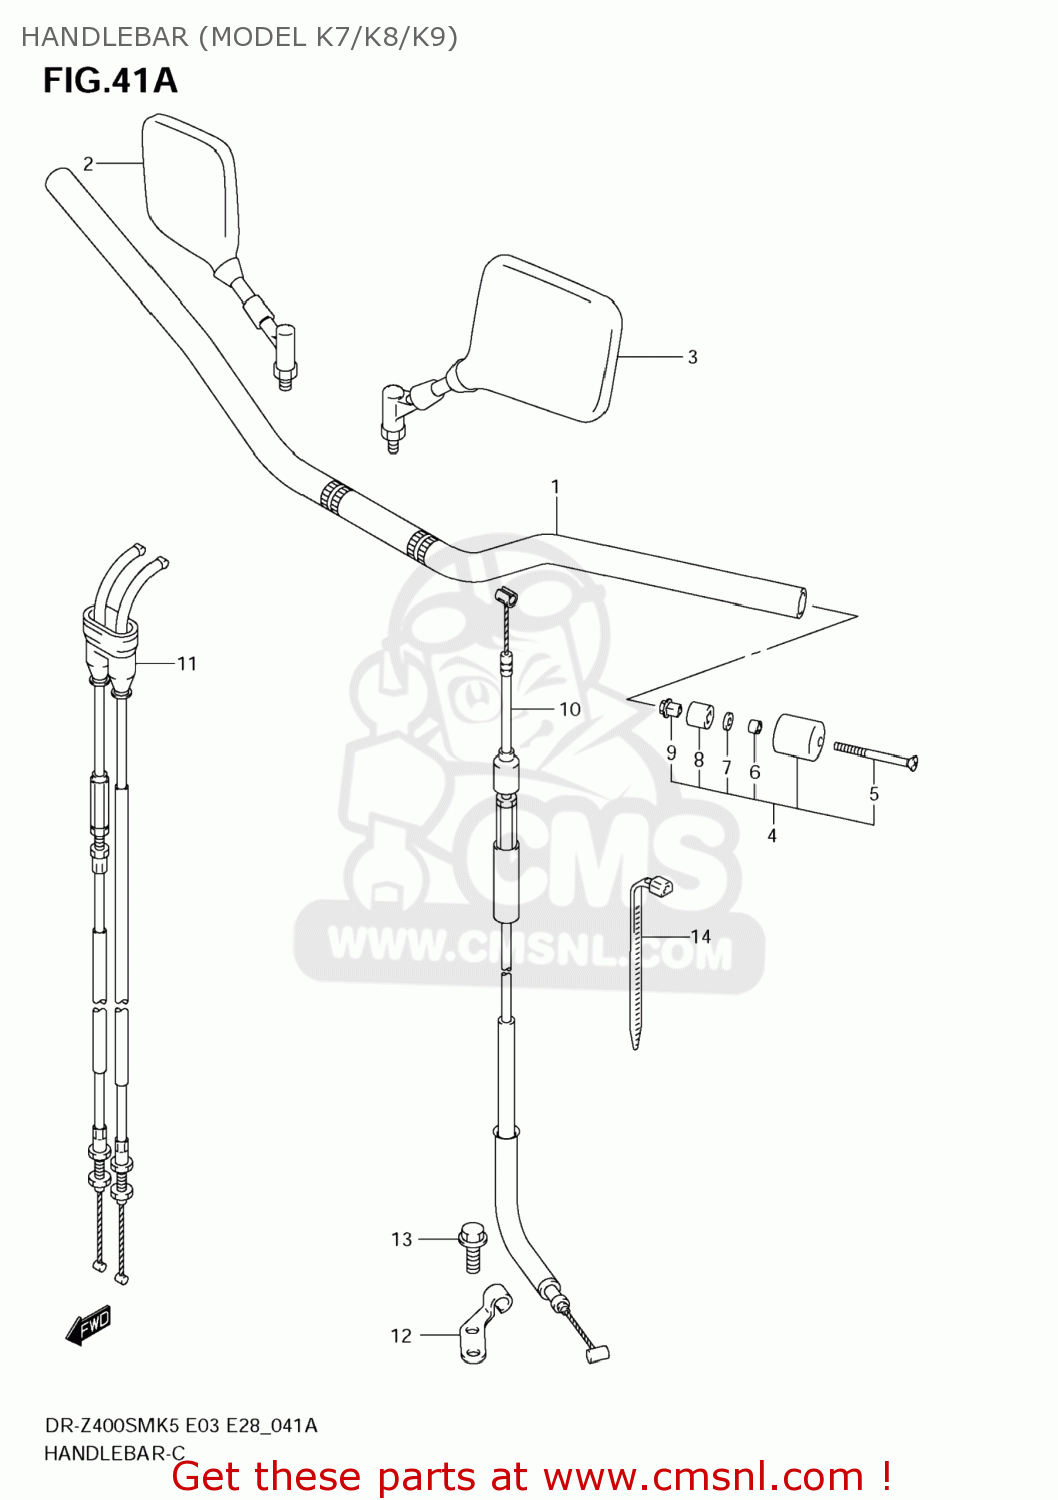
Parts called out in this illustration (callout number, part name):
1	HANDLEBAR
2	MIRROR ASSY,RR VIEW,R
3	MIRROR ASSY,RR VIEW,L
4	BALANCER SET,H
5	SCREW
6	SPACER(6.1X8X5.2)
7	WASHER
8	EXPANDER,HANDLE BALANCER
9	NUT,BALANCER
10	CABLE ASSY,CLUTCH
11	CABLE SET,THROTTLE
12	STOPPER,CLUTCH CABLE
13	BOLT
14	CLAMP(L:100)
